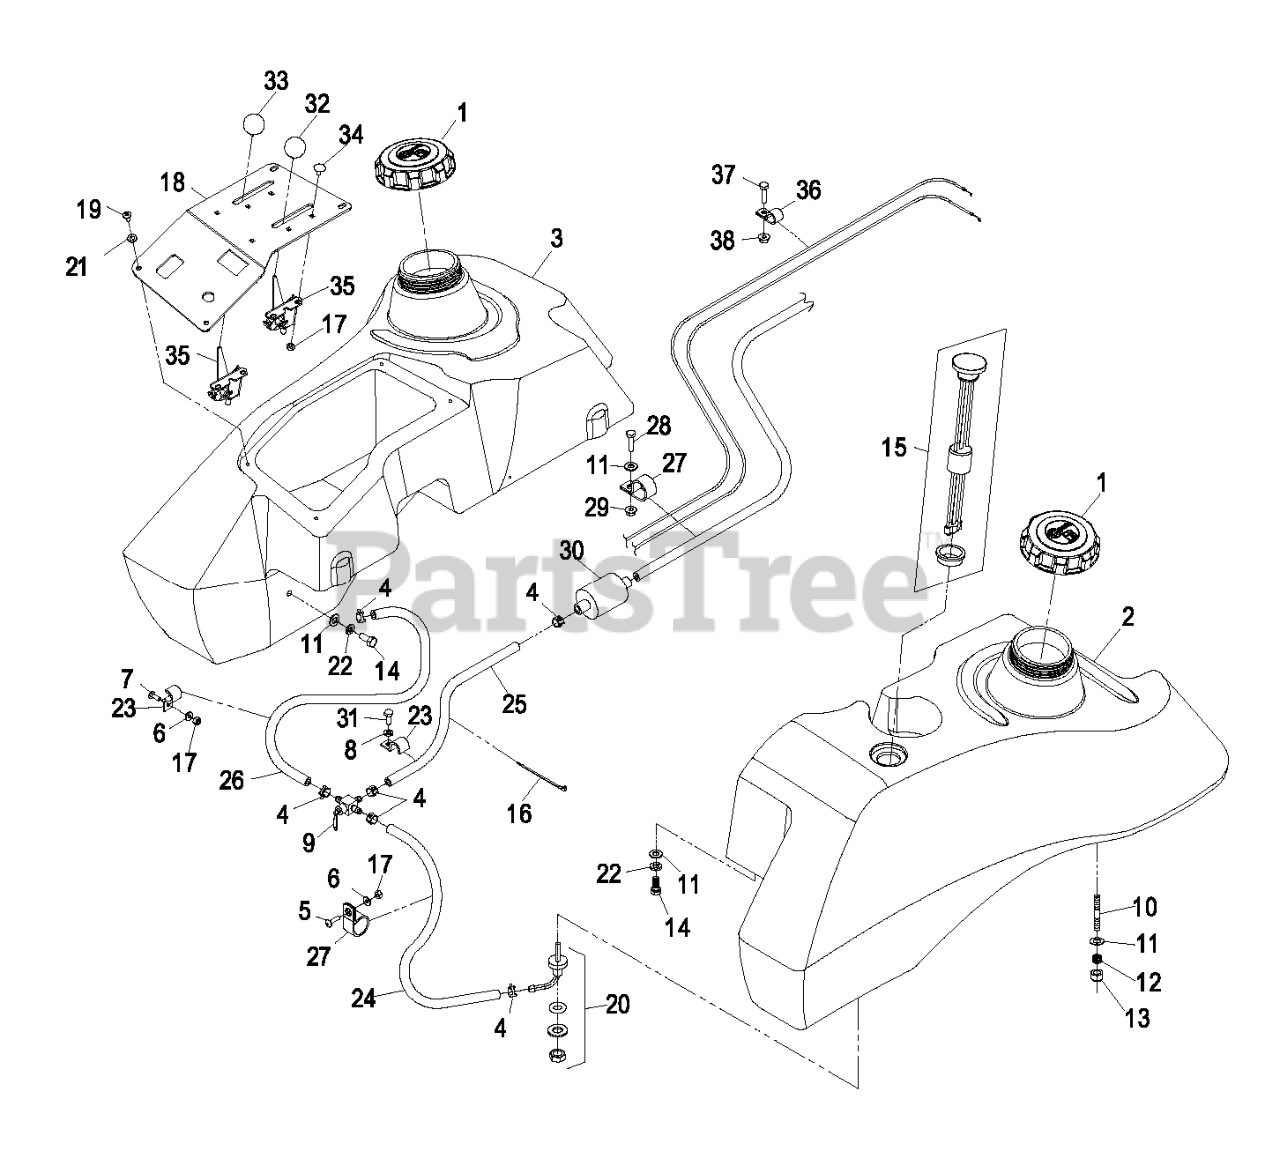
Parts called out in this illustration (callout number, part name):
2	KIT,FUEL TANK LH LZXS
3	KIT,FUEL TANK RH LZXS
5	SCREW-HEAD, TRUSS
6	WASHER-FLAT
7	BOLT-CARR
8	WASHER-LOCK
9	VALVE-FUEL
10	STUD
11	WASHER-PLAIN
12	SPRING-TANK, FUEL
13	NUT-LOCK, NI
14	SCREW-HH
15	KIT, CT FUEL GAGE REPL.
16	TIE-PLASTIC
17	NUT-LOCK, NI
18	KIT,CTRL PANEL W/DECALS L
19	SCREW-PTH
20	FITTING-FUEL, BULKHEAD
21	WASHER-SPRING
22	WASHER-LOCK
23	CLIP-HALF, LOOM
24	HOSE-FUEL
25	HOSE-LINE, FUEL
27	CLIP-LOOM
28	SCREW-HH
30	Briggs & Stratton Fuel Filter
31	SCREW-HH
32	KNOB-BALL
33	KNOB-BALL, BLACK
34	BOLT-CARR
35	CABLE-THROTTLE
36	CLIP-LOOM
37	SCREW-HH
